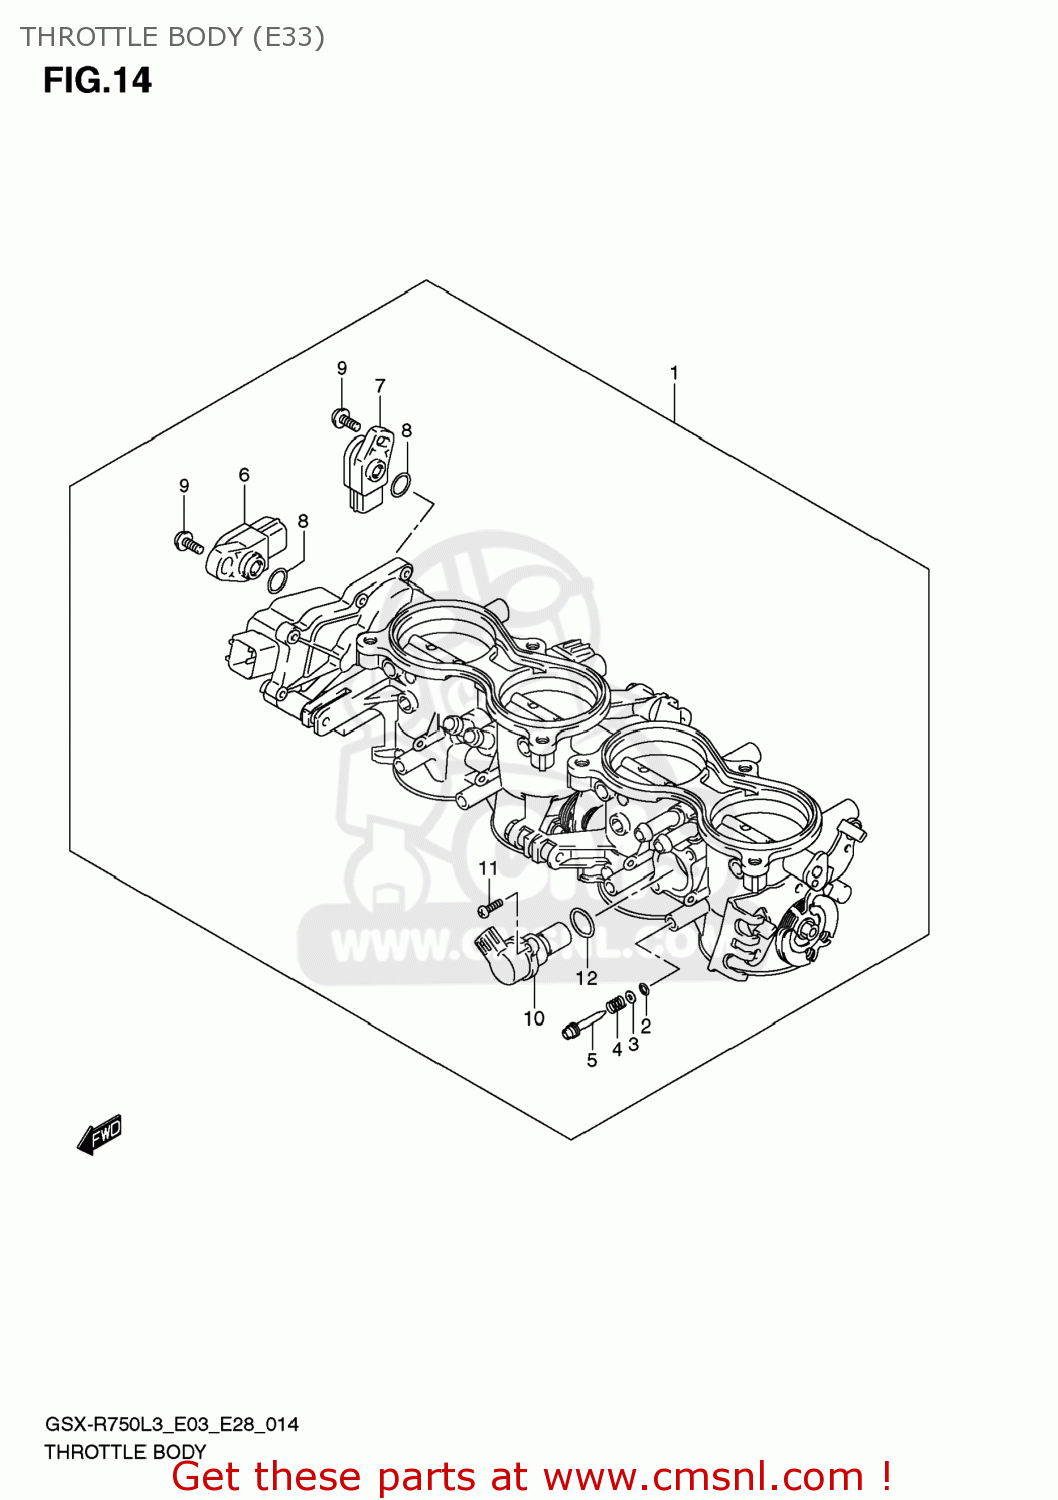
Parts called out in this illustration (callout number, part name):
1	BODY ASSY,THROTTLE
2	O RING,PILOT AIR SCREW
3	WASHER
4	SPRING,THROTTLE SCREW
5	SCREW
6	SENSOR
7	SENSOR
8	O RING
9	SCREW
10	MOTOR ASSY
11	SCREW
12	O RING
